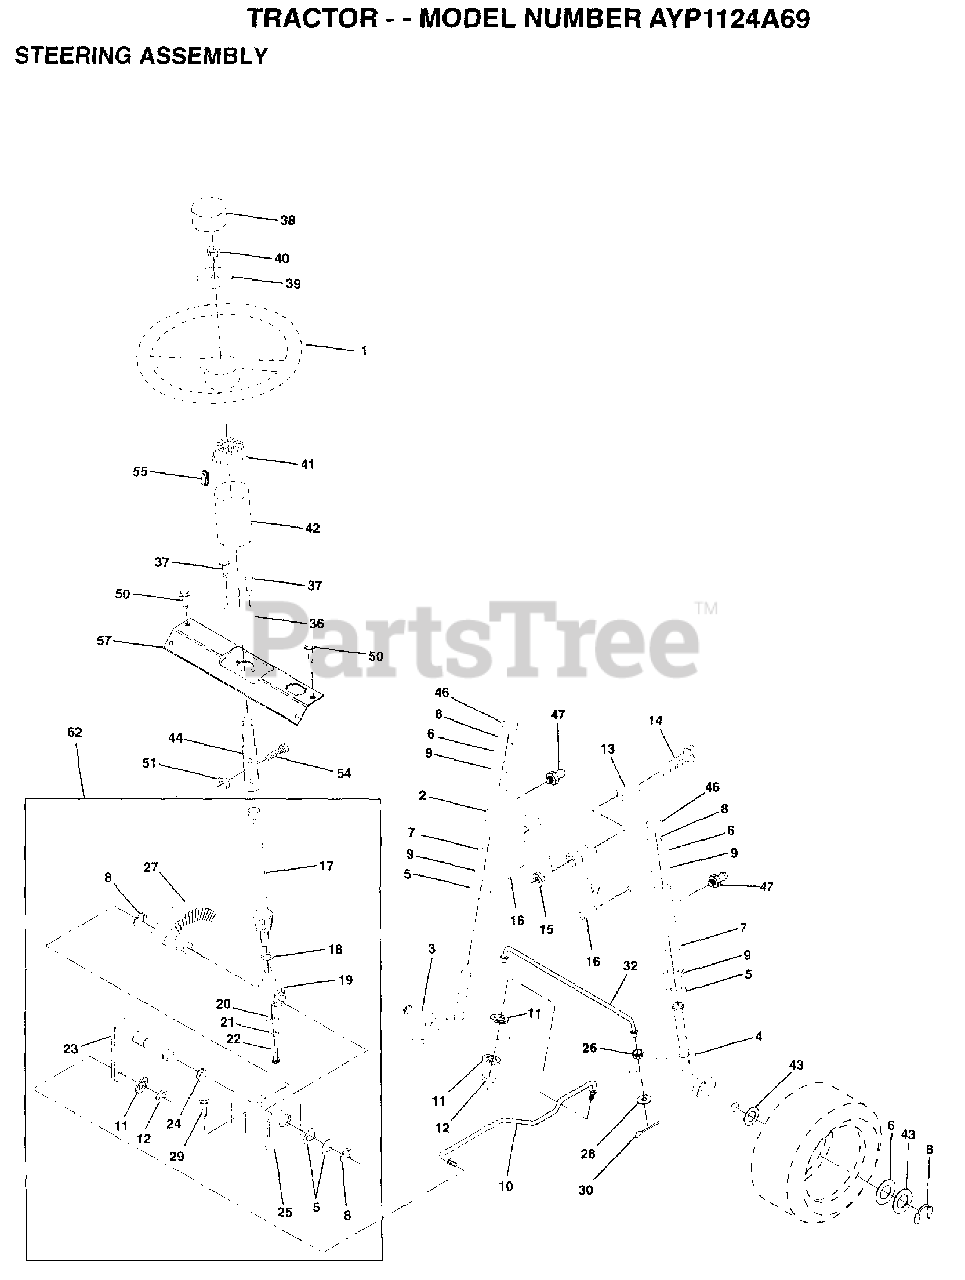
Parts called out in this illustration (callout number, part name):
1	WHEEL STR AYP BLK
2	AXLE ASM FRONT
3	SPINDLE LH
4	SPINDLE RH
5	WASHER .T
6	WASHER
7	WASHER
8	RING
9	COL. SRTG. BEAR.
11	LOCKWASHER
13	BEARING
14	BOLT HEX 5/8-11
15	"NUT-LOC,FLANGE LT"
16	AXLE PIN
17	SHAFT ASM STEERIN
18	THRUST WASHER
19	SUPPORT.SHAFT
21	LOCKWASHER
22	SCREW.SCKTHD.CAP
24	NYLINER T
25	"BRKT,STEERING"
26	BUSHING.DRAGLINK
27	GEAR SECTOR
28	WASHER
29	SCREW
30	COTTER PIN
32	TIE ROD
38	CAP STEER AYP
39	WASHER T
40	GRIPCO NUT
41	ADAPTER-WHEEL LT
42	BOOT SHAFT STEER
43	WASHER
46	CAP
47	ZERK M
50	SCREW HEX CRT
51	NUT
54	BOLT
55	CLIP TINNERMAN
57	SUPPORT SHAFT STR
